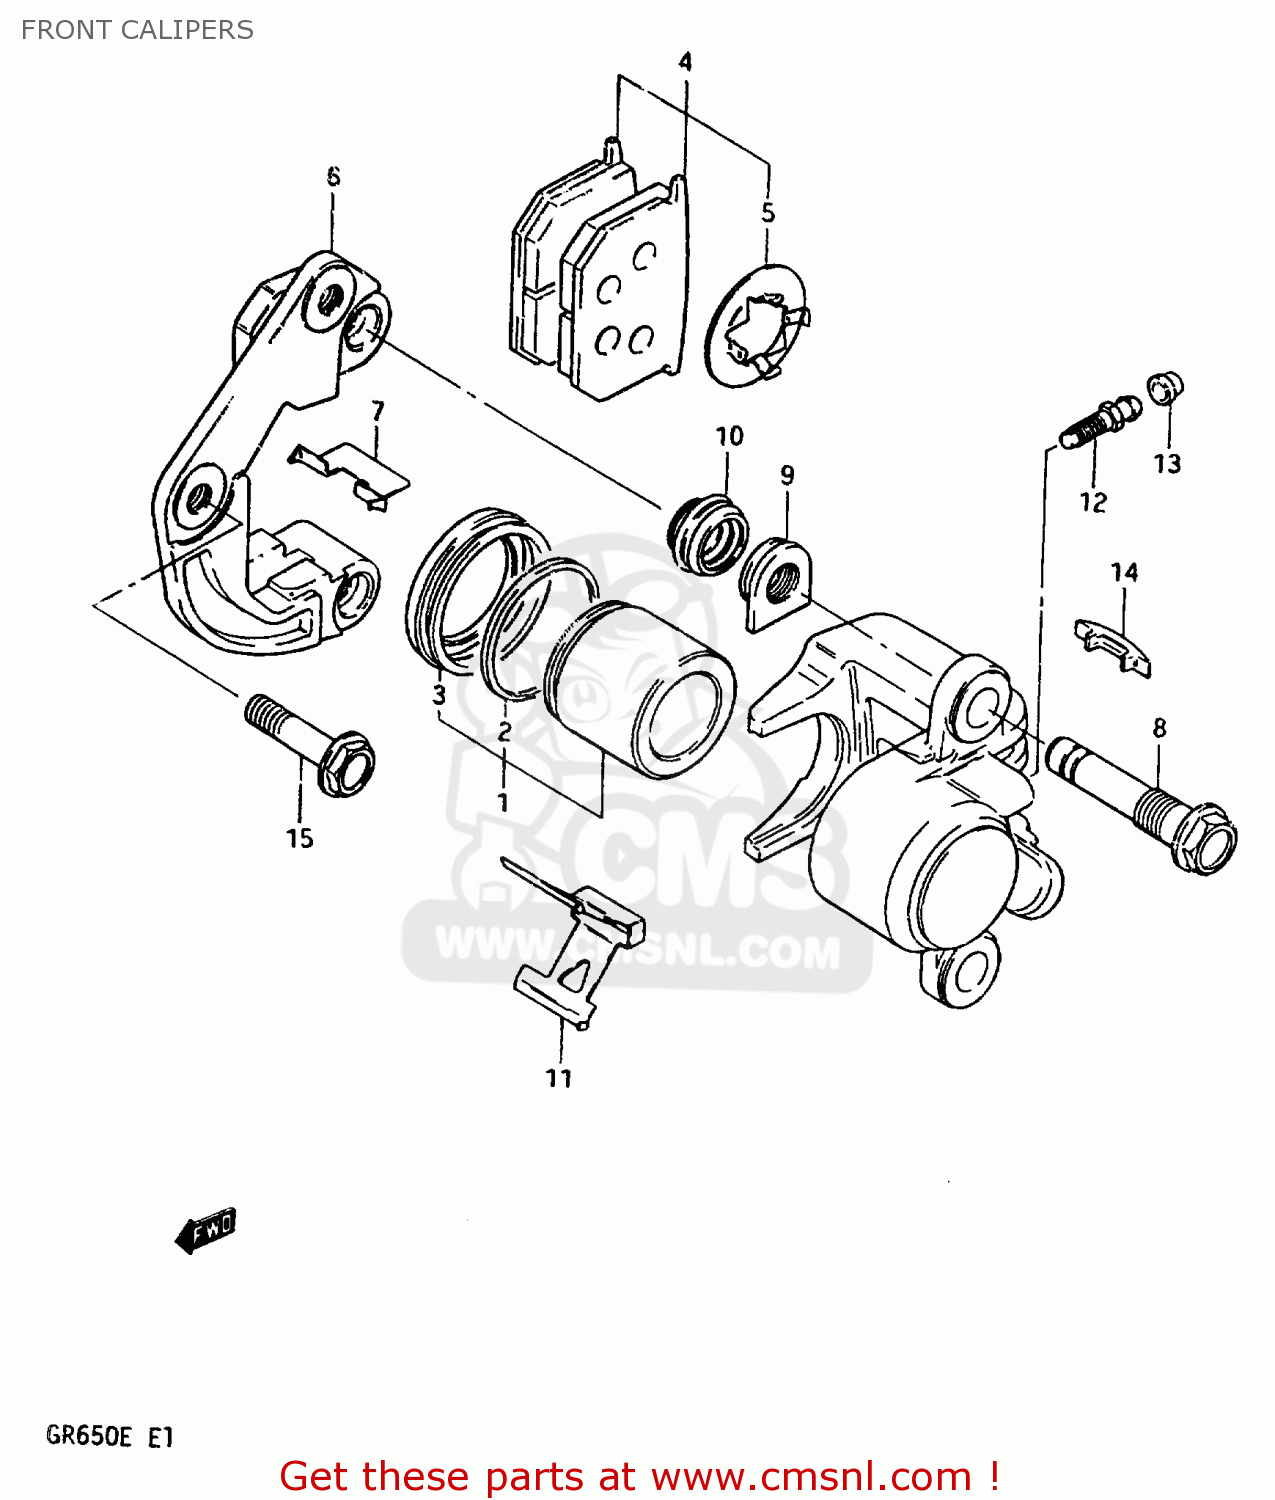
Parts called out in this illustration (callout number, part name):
1	PISTON SET
2	SEAL,PISTON
3	BOOT,PISTON
4	PAD & SHIM SET (NAS)
5	SHIM,PAD
6	HOLDER,CALIPER,LEFT
7	PAD,GUIDE
8	AXLE
9	NUT,CALIPER AXLE
10	BOOT
11	SPRING
12	BREATHER
13	CAP,BLEEDER PL
14	COVER,INDICATOR
15	BOLT(10X37)
